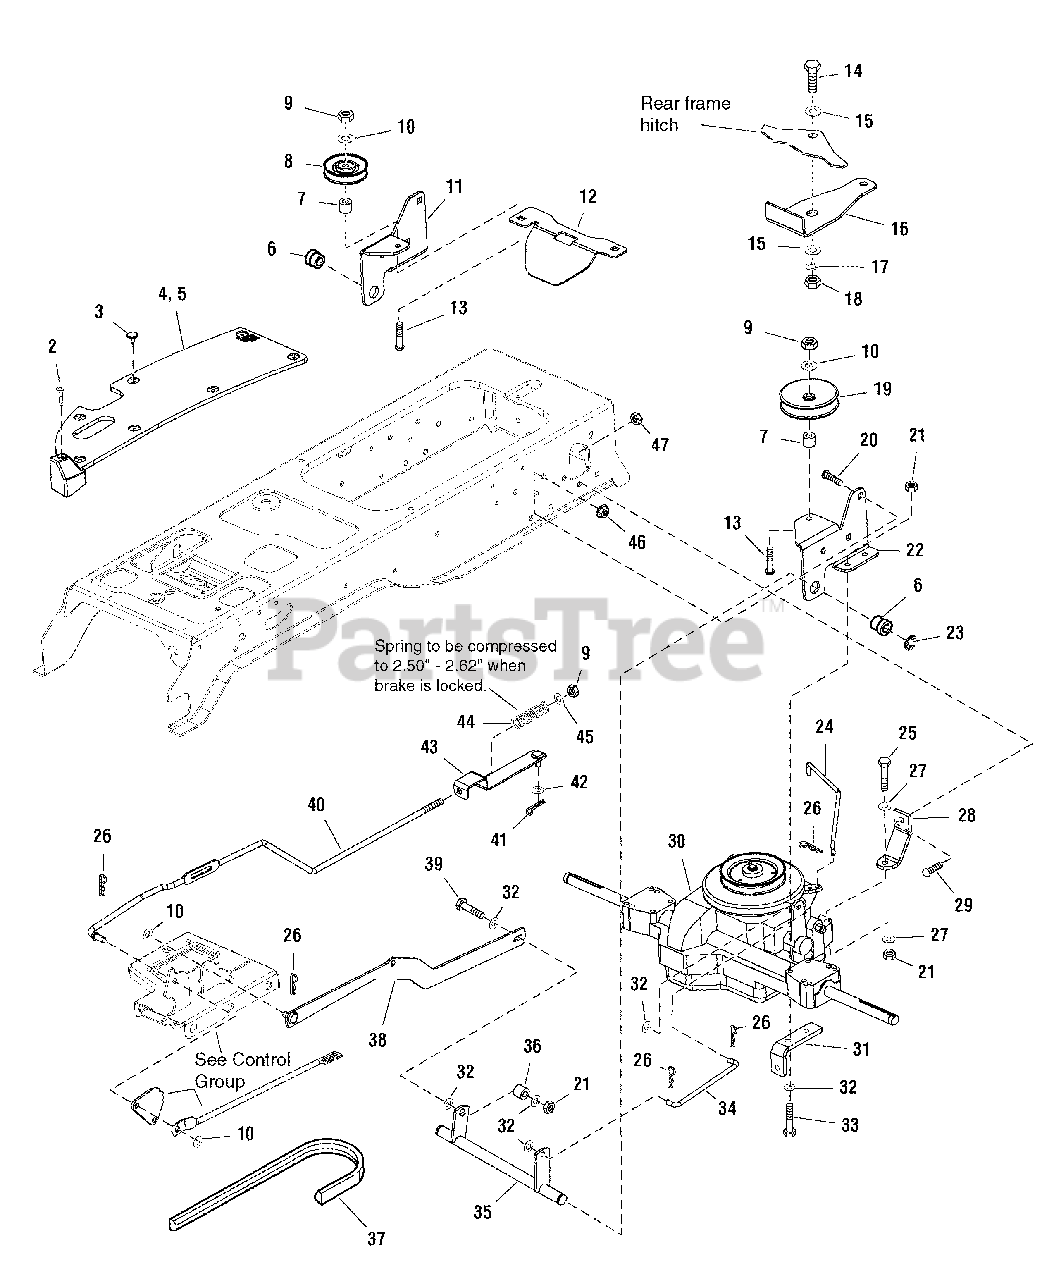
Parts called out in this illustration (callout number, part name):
2	SCREW, Pan Head Torx TT 1/4-20 x 1-1/4
3	FASTENER, Panel
4	PAD, Footrest, RH
5	PAD, Footrest, LH
8	PULLEY, 3" OD
9	NUT, Hex Lock ESNA, 3/8-16
10	WASHER
11	SUPPORT, Transmission, RH
12	BRACKET, Chute
13	CARRIAGE BOLT, 3/8-16 x 2-1/4
14	CAPSCREW, Hex Head, 1/2-13 x 1-1/4
15	WASHER
17	LOCKWASHER, 1/2
18	NUT, Hex 1/2-13
19	PULLEY, 4" OD
20	CARRIAGE BOLT, 3/8-16 x 1
21	NUT, Hex Lock ESNA, 5/16-18
22	SUPPORT, Transmisson, LH
25	CAPSCREW, Hex Head, 5/16-18 x 2
26	PIN, Quick
28	STRAP, Torque
29	CARRIAGE BOLT, 5/16-18 x 3/4
30	TRANSMISSION ASSEMBLY, K46
31	ANCHOR, Spring
33	CAPSCREW, Hex Head, 5/16-18 x 2-3/4
35	SHAFT ASSEMBLY
37	V-BELT, Drive
38	ARM & PIN ASSEMBLY
39	CAPSCREW, Hex Head, 5/16-18 x 1
41	PIN, Cotter
42	WASHER
43	BRACKET & PIN ASSEMBLY
44	SPRING, Compression
46	NUT, Hex KEPS, 3/8-16
47	NUT, Hex KEPS, 5/16-18
